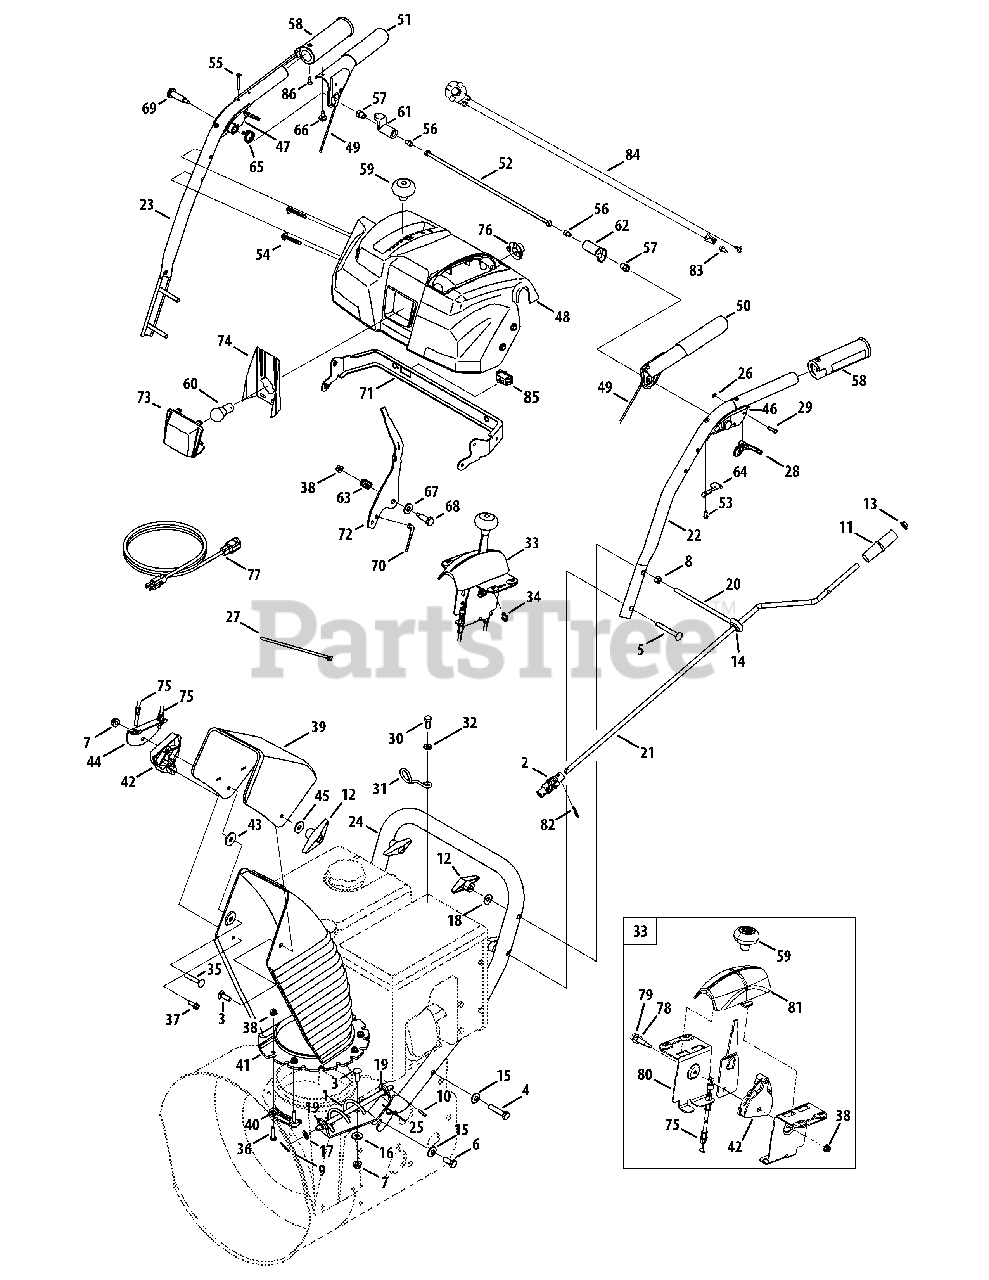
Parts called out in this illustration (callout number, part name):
1	Chute Crank Assembly
2	Joint Block Assembly
3	Screw, Carriage, 5/16-18 x 1.0
4	Screw, Hex, 3/8-16 x 2.00 Lock
5	Screw, Carriage, 5/16-18 x 2.5
6	Screw, Hex, 3/8-16 x 1.0 Lock, Gr5
7	Flange Lock Nut, 5/16-18
8	Hex Nut, 5/16-18
9	Internal Cotter Pin
10	Spring Pin
11	Knob, Crank
12	Wing Knob
13	Cap, Push, 3/8
14	Grommet, Rubber
15	Washer, Bel, .375 x .87 x .063
16	Washer, Flat, .349 x .879 .063
17	Washer, .375 x .738 x .063
18	Washer, Belleville, .34 x .872 x .06
19	Plastic Bushing, .380 I.D.
22	Handle, Upper - LH
23	Handle, Upper - RH
24	Handle, Lower
25	Chute Crank Bracket
26	Ring, Retainer
27	Cable Tie
30	Hex Head Screw, MB 1.25
31	Cable Guide
32	Flat Washer, .330 x .630 x .0635
33	2-Way Chute Control™ Assy
34	Hi-Lo Screw, 1/4-15 x 0.5
35	Bolt, Carriage, 5/16-18 x 1.75
36	Screw, 1/4-20 x 1.00
37	Hi-Lo Screw, 1/4-15 x .75
38	Flange Lock Nut, 1/4-20
39	Upper Chute
40	Chute, Flange Keeper
41	Lower Chute
42	Chute Tilt Cable Guide
43	Flat Washer
44	Cable Bracket
45	Washer, Flat, .349 x .879
46	Handle Clutch Lock - LH
47	Handle Clutch Lock - RH
48	Handle Panel
49	Cable Assembly, Auger/Drive
50	Handle Engage Assy - LH
51	Handle Engage Assy - RH
52	Rod Ass’y, Clutch Lock Pivot
53	Screw, #8-16 x 0.50
54	Screw, 1/4-20 x 1.625
55	Screw, #10-24 x 0.375
56	Screw, 1/4-20 x.375
57	Shoulder Nut, 1/4-20
58	Heated Grip
59	Shift Knob
62	Clutch Lock Cam
63	Compression Spring
64	Clutch Lock Spring
65	Torsion Spring
66	Rubber Bumper
67	Flat Washer, .385 x .87 x .06
68	Shoulder Screw
69	Shoulder Screw, 1/4-20 x 1.345
70	Speed Selector Cable
71	Panel Bracket
73	Lens Panel
74	Reflector Label
75	Cable, Chute Tilt
76	Light Socket
77	Extension Cord, 110V
78	Washer, Spring, .39 x .625 x .012
79	Screw, Shoulder, .31 x .995:1/4-20
80	Bracket, Mounting
81	Cover, Tilt Cover
82	Internal Cotter Pin
83	1/4-20 x .50
84	Wire Harness
85	Heated Grip Switch
86	Screw, #10-16 x .625
